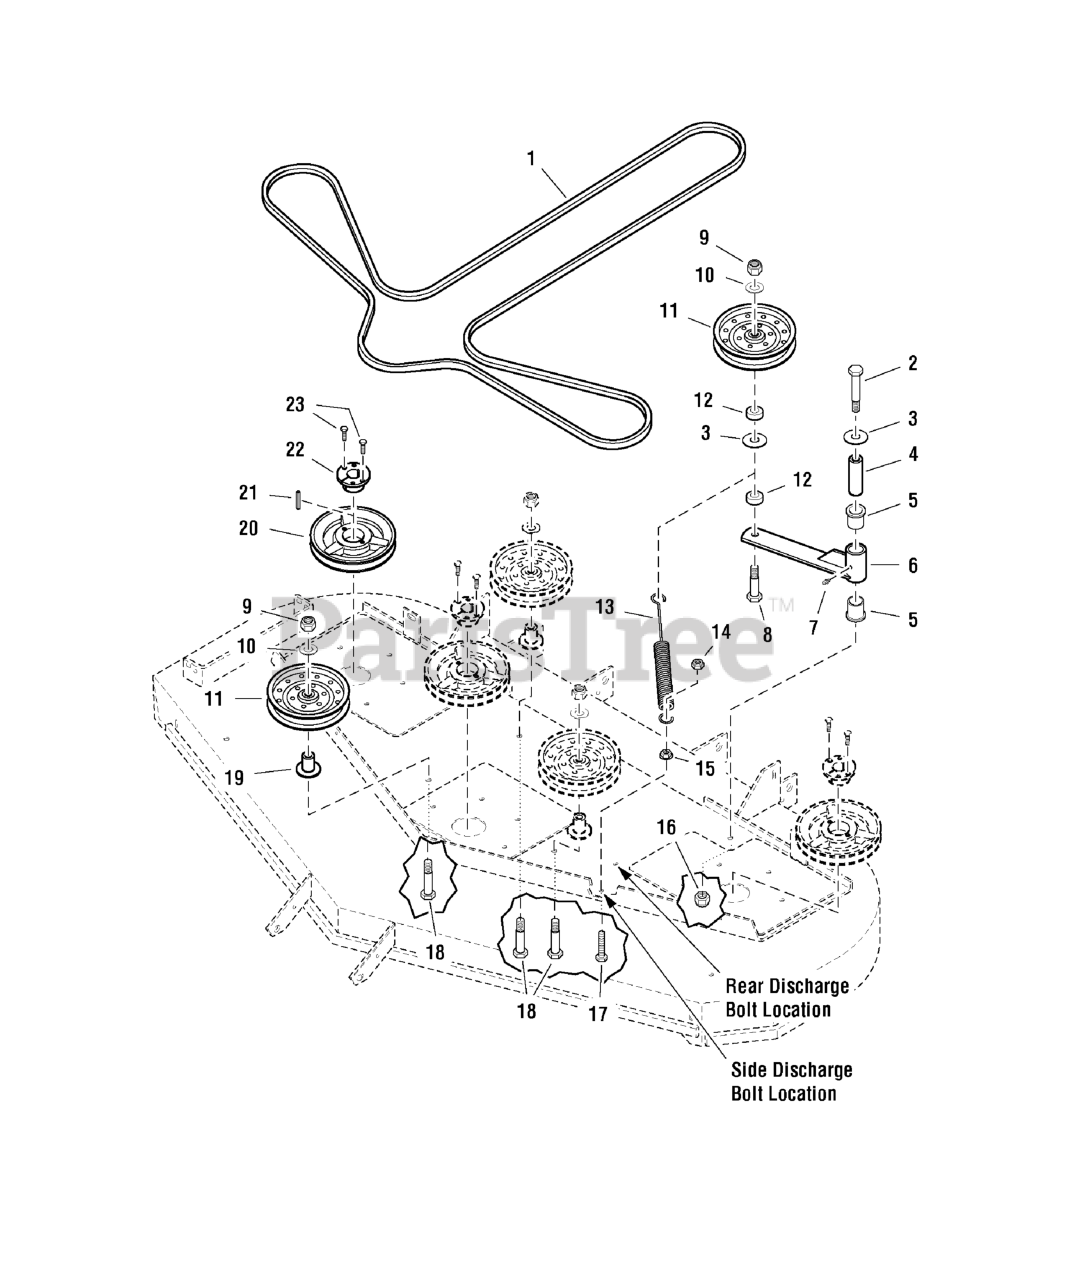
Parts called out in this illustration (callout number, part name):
2	BOLT, 1/2-13 x 4-1/2
3	WASHER, 1/2" USS
4	SPACER, .52 x 1.00 x 3.50
5	BUSHING, FLANGE
6	GREASE FITTING
7	IDLER ARM
8	BOLT, 1/2-20 x 3
9	NUT, Hex, Nylon Lock, 1/2-20
10	WASHER, 1/2 SAE
12	SPACER, .52 x 1.00 x .44
13	SPRING, Extension, Swivel End
14	NUT, 3/8-16 HEX NYLON LOCK
15	NUT, 3/8-16 Hex Serrated Flange
16	NUT, 1/2-13 HEX NYLON LOCK
17	BOLT, 3/8-16 x 1-3/4 TFL
18	BOLT, 1/2-20 x 3-1/2
19	IDLER PULLEY MOUNT
20	PULLEY, Spindle
21	KEY, 1/4 SQ. X 1-1/2
22	BUSHING, Tapered Hub
23	BOLT, 1/4-20 X 1" GD5 CZ
